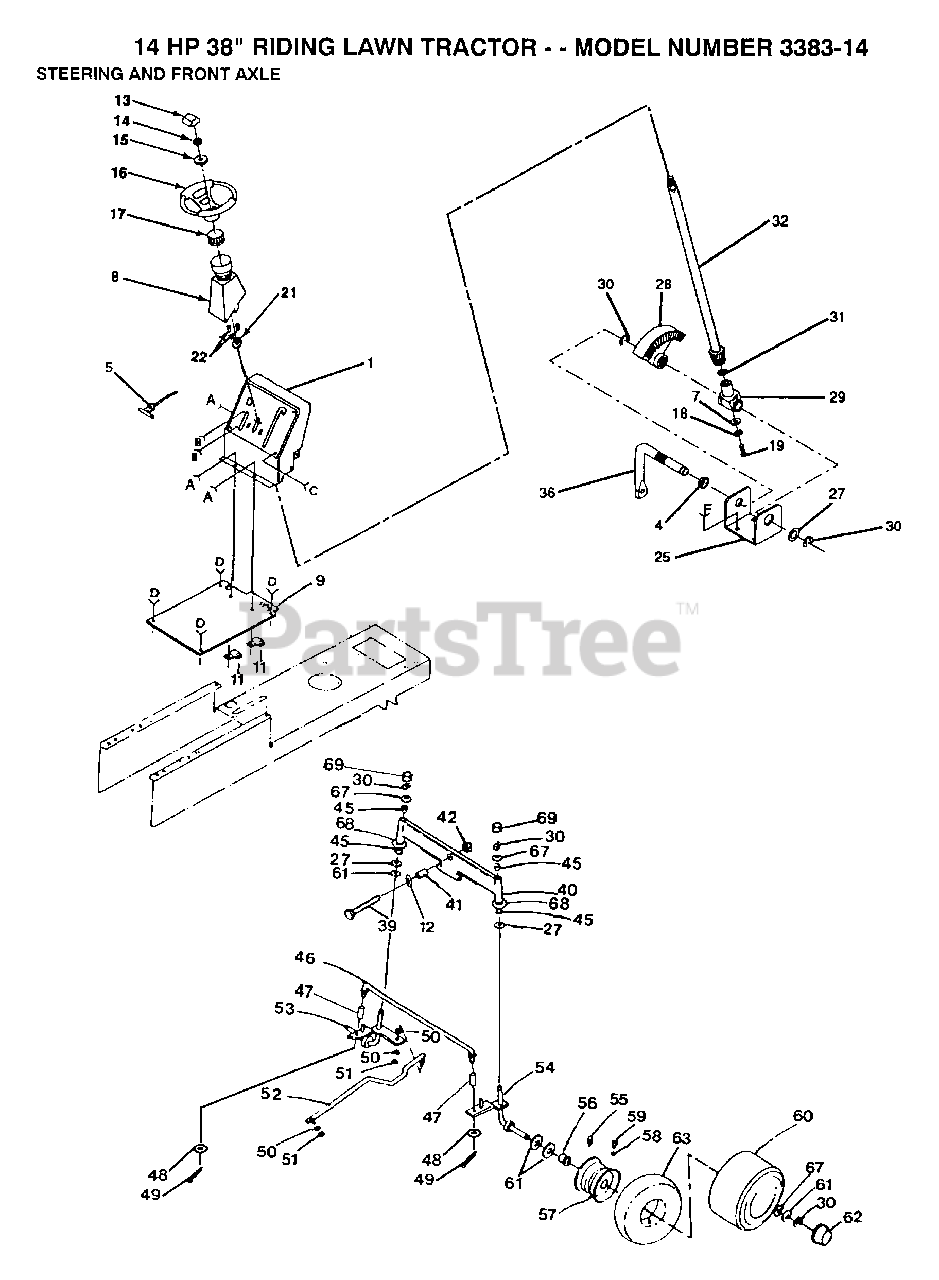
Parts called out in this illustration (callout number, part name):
4	NYLINER T
8	"TUBE, STR SHAFT"
11	CLIP T
13	INSERT-WHEEL LT
15	WASHER
17	ADAPTER LT
18	LOCKWASHER
19	"SCREW,SPECIAL"
21	"BUSHING,STEERING"
25	"BRKT,STEERING"
27	WASHER .T
29	SUPPORT.SHAFT
30	RING
31	THRUST WASHER
39	BOLT LT
41	BEARING
45	COL. SRTG. BEAR.
48	WASHER
49	COTTER PIN
50	LOCKWASHER
53	SPINDLE-LH LT
55	FITTING LT
56	"FLANGE, BEARING"
58	VALVE CAP
59	VALVE STEM LT
61	WASHER
62	HUB CAP
63	TUBE.5.3/4.5/6
67	WASHER
68	WASHER
69	PUMP.2003081.
